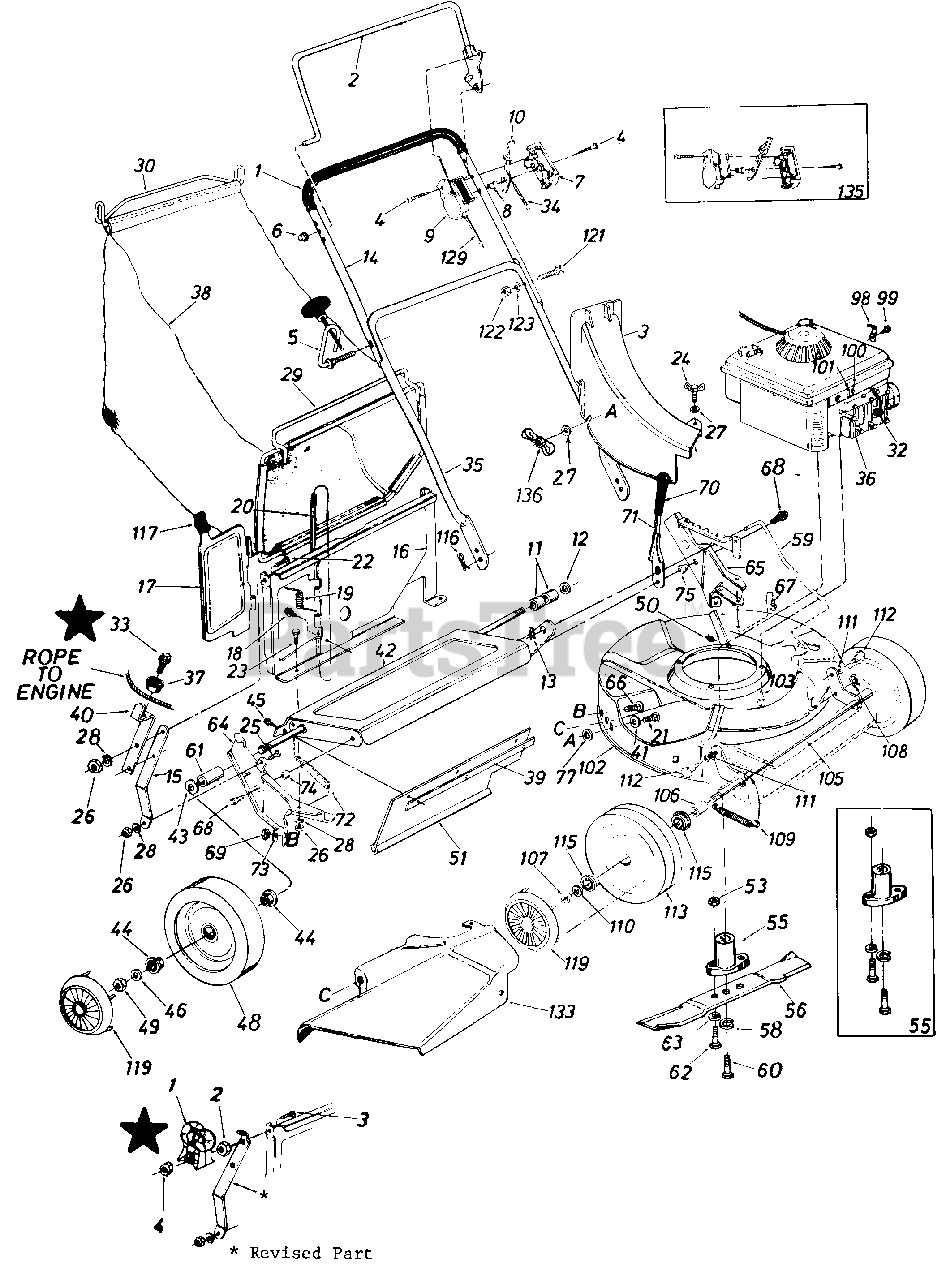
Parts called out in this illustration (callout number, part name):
2	Control Handle Ass'y. -L.H.
3	Top Discharge Chute Ass'y.
4	Truss Mach. Scr. #12 x 1.50" Lg.
5	ope Guide Bolt
6	Cap Speed Nut .31 Dia.
7	Control Panel Half
8	Control Disc Pin
9	Clutch Panel Half
10	Throttle Control Lever
11	Spacer.526" I.D. x .690" O.D. x .640" Lg.
12	Fl-Wash. .531" I.D. x .930" O.D.
13	Intern. Cotter Pin 5/16" Dia.
14	Upper Handle Chrome
15	Panel Support Brkt.
16	Top Catcher Panel
17	Top Door
18	Hex "B" Tap Scr. #10 x .38" Lg.
19	Torsion Spring .20" I.D. x 1.14" Lg.
20	Pivot Pin .187" Dia. x 7.25" Lg.
21	Carriage Bolt 1/4-20 x .62"
22	Truss Mach. Scr. 1/4-24 x 75 Lg.
23	Hex Bolt 1/4-20 x .50" Lg.
24	Wing Bolt1/4-20 x .62" Lg.
25	Truss Mach. Scr. 1/4-20 x .62" Lg.
26	Hex Nut 1/4-20 Thd.
27	Fl-Wash. .280" I.D. x .620" O.D.
28	L-Wash. 1/4" I.D.
29	Front Grass Catcher Frame
30	Grass Catcher Handle
32	Spark Plug Insulator
33	Hex Wash. Hd. Tap Scr. 3/8-16 x 1.00" Lg.
34	Throttle Control Wire 58.0" Lg.
35	Lower Handle Chrome
36	Engine
37	Flanged Ball Bearing 3/8" I.D.
38	21" Top Discharge Grass Bag
39	Retaining Strip
40	Rope Guide Brkt.
41	Fl-Wash. .344" I.D. x .62" O.D.
42	Rear Axle Ass'y.
43	Fl-Wash. .531" I.D. x .930" O.D.
44	Flange Ball Bearing 1/2" I.D.
45	Hex AB-Tap Scr. 1/4 X .62" Lg.
46	Fl-Wash. .531" I.D. x .930" O.D.
48	Rear Wheel Ass'y. Comp. 8 x 1.75
49	Hex L-Nut 1/2-20 Thd.
51	Rear Flap 3.75" x 17.30" Lg.
53	Hex Nut 5/16-24 Thd.
55	Blade Adapter Kit
56	21" Blade
58	L-Wash. 3/8" I.D. H.D.
59	Height Adj. Rod 1.50" x 19.42" Lg.
60	Hex Bolt 3/8-24 x 2.25" Lg. (Grade 5)
61	Spacer.51" I.D. x .69" O.D. x.690" Lg.
62	Hex Bolt 5/16-24 x 1.00" Lg. (Grade 5)
63	L-Wash. 5/16" I.D.*
64	R.H. Handle Wheel Brkt. Ass'y.
65	L.H. Handle Wheel Brkt. Ass'y.
66	Carriage Bolt 5/16-18 x .62" Lg .
67	Hex Wash. Hd. B-Tap Scr. 5/16-18
68	Hex Wash. Hd. TT-Tap Scr. 3/8-16
69	Hex Nut 5/16-18 Thd.
71	Height Adj. Lever 1.25 x 8.5" Lg.
72	Extension Spring .50" O.D. x 3.80" Lg.
73	Bell-Wash. .345" I.D. x .88" O.D.
74	Spacer.385" I.D. x .502" O.D. x .270" Lg.
75	Shld. Spacer .500" Dia. x .100
77	Bolt Retainer 1/4 X .50" O.D.
98	Throttle Control Cable Clip
99	Hex B-Tap Scr. #10 x .38"
100	Hex Sems Bolt #10-32 x .62" Lg.
101	Casing Clamp
102	21" Deck Ass'y.
103	Hex Wash Hd. TT-Tap Scr. 3/8-16
105	Front Axle Ass'y.
106	Sleeve .526" I.D. x .690" O.D. x .880" Lg.
107	Hex L-Nut 1/2-20 Thd.
108	Intern. Cotter Pin 5/16" Dia.
109	Extension Spring .50" O.D. x 3.20" Lg.
110	Fl-Wash. .531" I.D. x .930" O.D.
111	Intern. L-Wash. 3/8 x .56" O.D.
112	Shld. Bolt .623" Dia. x .425
113	Front-Wheel Ass'y. Comp. 7 x 1.75
115	Flange Ball Bearing 1/2" I.D.
116	Intern. Cotter Pin 5/16" Dia.
117	Door Grip x 2.5
119	Hub Cap Plastic
121	Curved Carr. Bolt 5/16-18 x 1.38" Lg.
122	Hex Nut 5/16-18 Thd
123	L-Wash. 5/16" I.D.
129	Control Cable 43" Lg.
133	Side Chute Deflector
135	Kit Control Housing Comp.
136	Wing Nut
